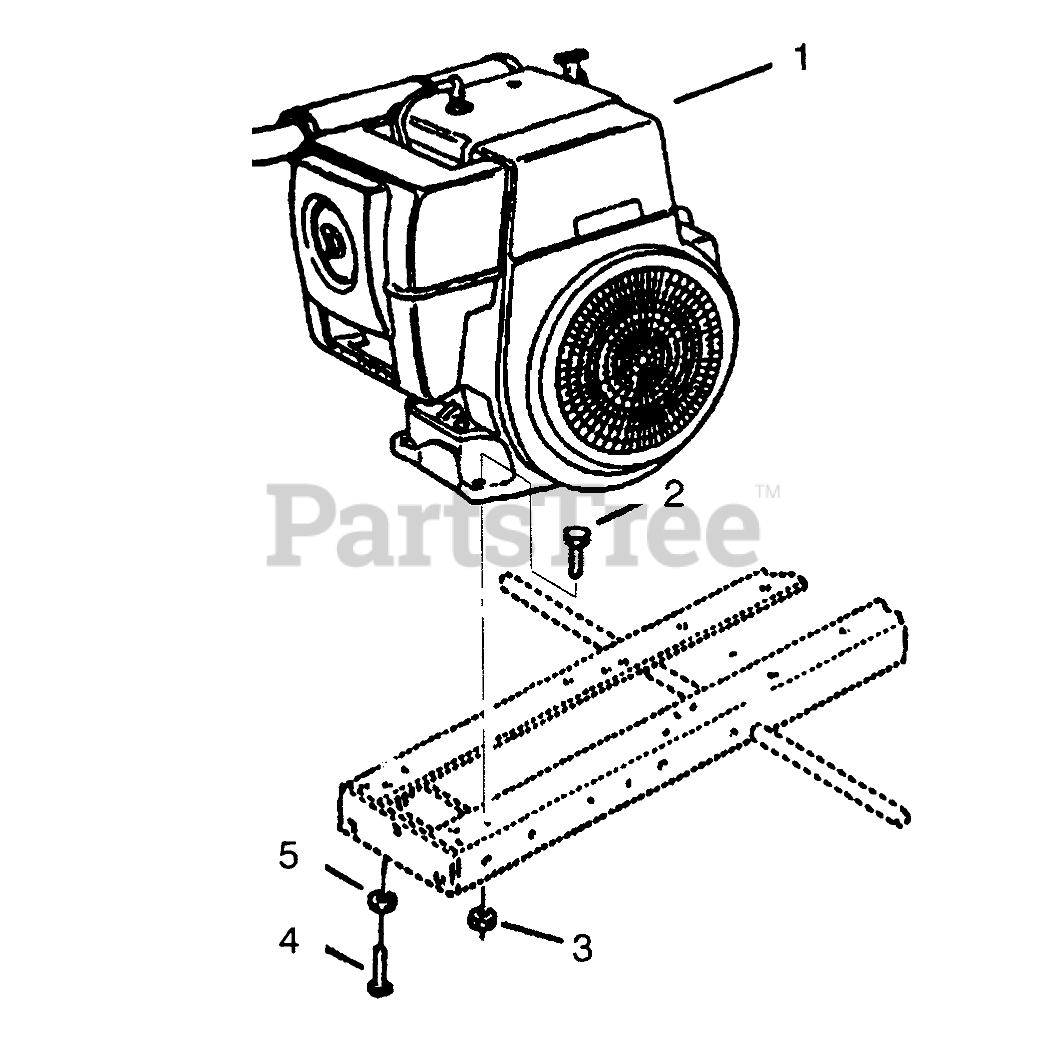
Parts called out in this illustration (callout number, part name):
1	Engine-14HP
2	SCREW-HH
3	NUT-LOCK, NI
4	SCREW-HH
5	Washer-Lock
